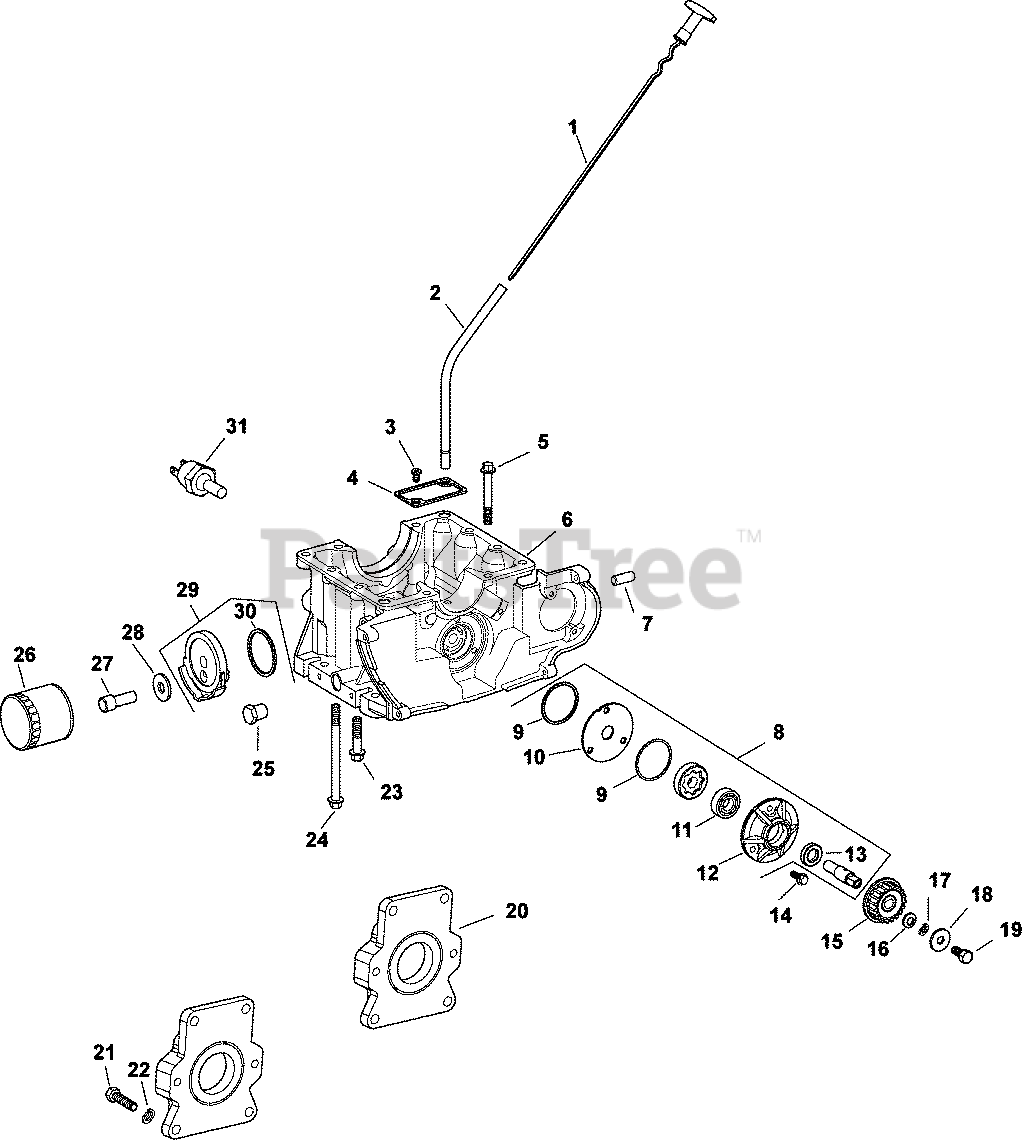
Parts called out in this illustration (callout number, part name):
1	DIPSTICK - DISCONTINUED
2	TUBE, DIPSTICK - DISCONTINUED
3	SCREW, TORX COUNTRSUNK HD
4	SCREEN, OIL PICK-UP - (#DSC)
5	SCREW, FLG M8X1.25X70
6	CRANKCASE
7	VALVE, PISTON RELIEF
8	PUMP ASSEMBLY, OIL - DISC.
9	O-RING - DISCONTINUED
10	PLATE, WEAR - DISCONTINUED
11	BEARING, BALL
12	COVER, OIL PUMP - DISCONTINUED
13	SEAL, OIL - DISCONTINUED
14	SCREW, FLG M6x1.0x20
15	SPROCKET, OIL PUMP - (#DSC)
16	WASHER, SPRING 13 MM
17	WASHER, SPRING LOCK 1/4"
18	WASHER, FLAT 1/4"
19	SCREW, HEX HEAD MACHINE
20	ADAPTER, PUMP
21	SCREW, CAP HD 7/16-14x2"
22	WASHER, SPRING LOCK 7/16"
23	SCREW, FLG M8X1.25X40 - (#M851040S)
24	SCREW, FLG M8X1.25X115
25	PLUG, HD PIPE 3/8"
26	OIL FILTER
27	NIPPLE, OIL FILTER
28	WASHER, FLAT - DISCONTINUED
29	KIT, PLASTIC FILTER ADAPTER - DISCONTINUED
30	O-RING - DISCONTINUED
31	KIT, OIL SENTRY(PRESSURE) - (#DSC)
